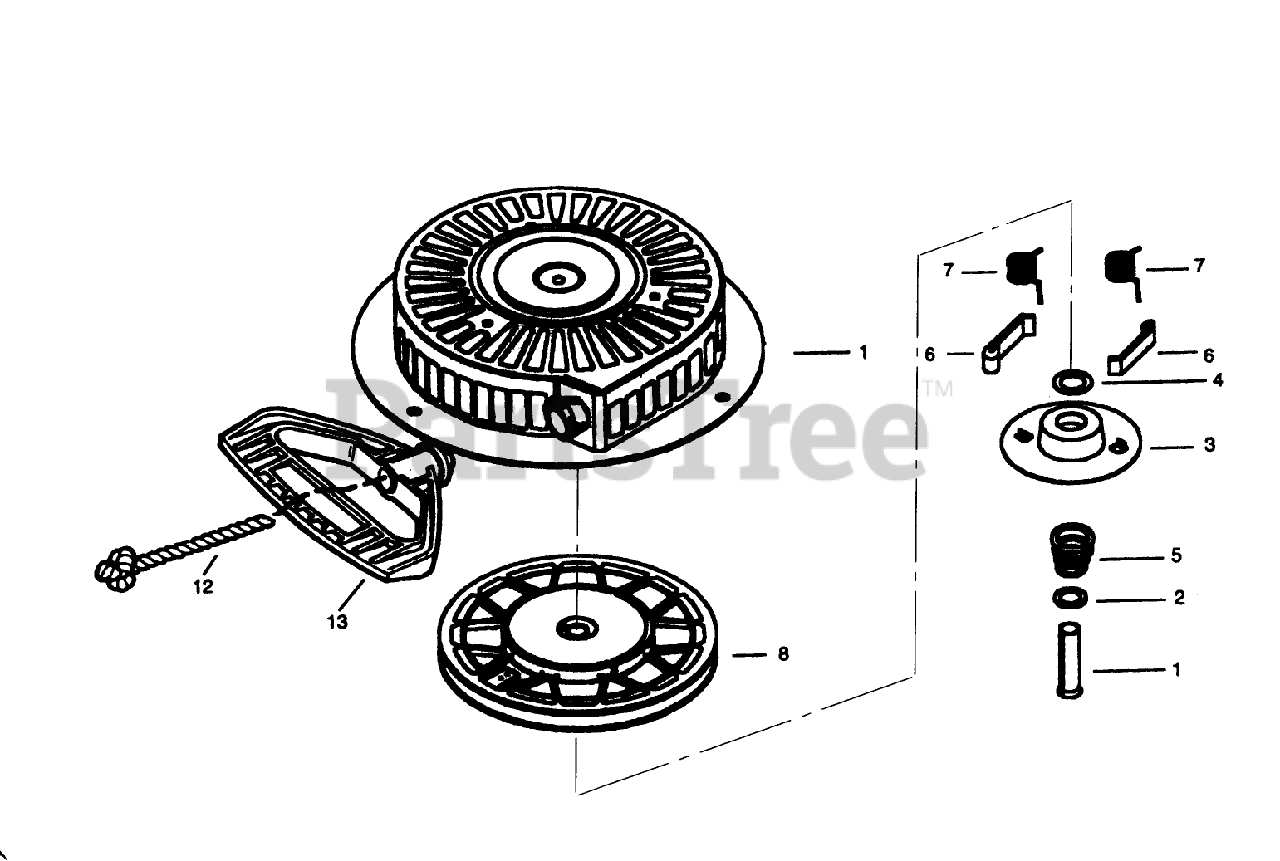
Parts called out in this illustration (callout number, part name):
1	Pin, Spring (Incl. Ref. #7)
2	Washer
3	Retainer
4	Washer
5	Spring-Brake
6	Dog-Starter
7	Spring-Dog
8	Pulley and Rewind Spring ASM
11	Starter Housing ASM
12	Rope-Starter (98 cut to length)
13	Handle-Starter, Mitten Grip
